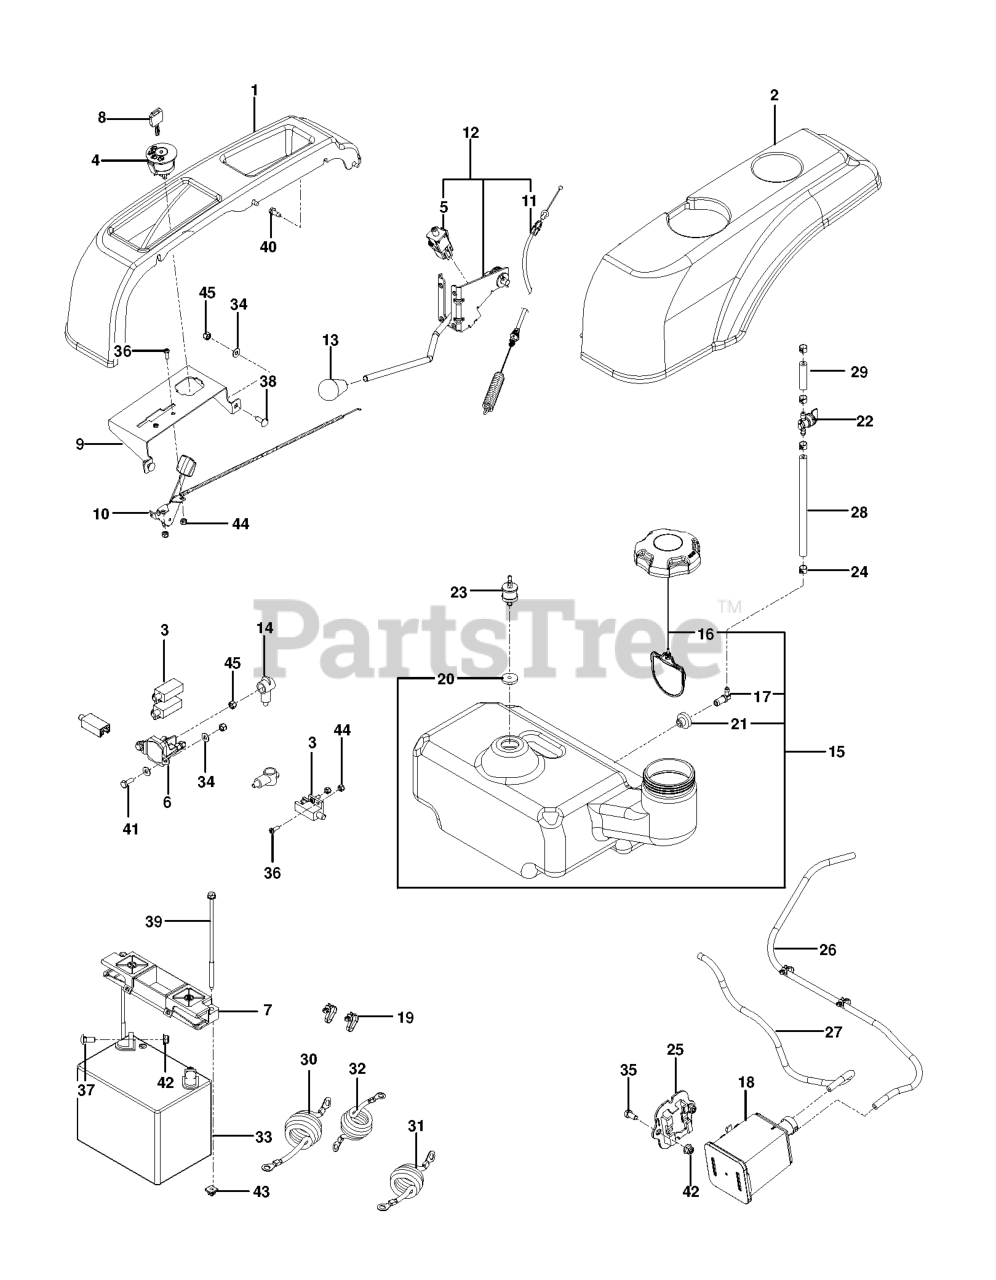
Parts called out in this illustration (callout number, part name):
1	FENDER RH
2	FENDER LH
4	IGNITION SWITCH
5	SWITCH INTERLOOK PUSH-IN
6	SOLENOID
7	BATTERY HOLD DOWN
10	THROTTLE CABLE
13	KNOB - SHIFT
14	TERMINAL COVER-SM
15	FUEL TANK ASM SMALL
16	CAP, FUEL
18	CANNISTER, CARBON
19	TIE WRAP, 8-3/8", W/CLIP
20	GROMMET, CHECK VALVE
21	RUBBER GROMMET
22	FUEL VALVE
23	VALVE.FUEL.CHECK
24	HOSE CLAMP
25	BRACKET, CANISTER
26	FUEL LINE 33"
27	HOSE, FUEL, 3/16" X 20"
28	HOSE 1/4 X 8
29	HOSE 1/4 X 2"
30	POST.CABLE LONG
31	CABLE POSITIVE, LONG
32	BATTERY CABLE, NEGATIVE
34	WASHER 1/4 SAE
36	SCREW #10-24 X 5/8
37	BOLT 5/16C X 3/4" CARRIAGE
38	RHSNB 1/4C X 3/4
39	BOLT - 1/4-20 X 7.5
40	SCREW 1/4 X 5/8
41	HCS 1/4C X 3/4 HCS
42	5/16-18 NYLOC FLANGE NUT
43	PUSH NUT-NYLON
44	NUT 10-24 NYLOC
45	NUT 1/4-20 NYLOC
